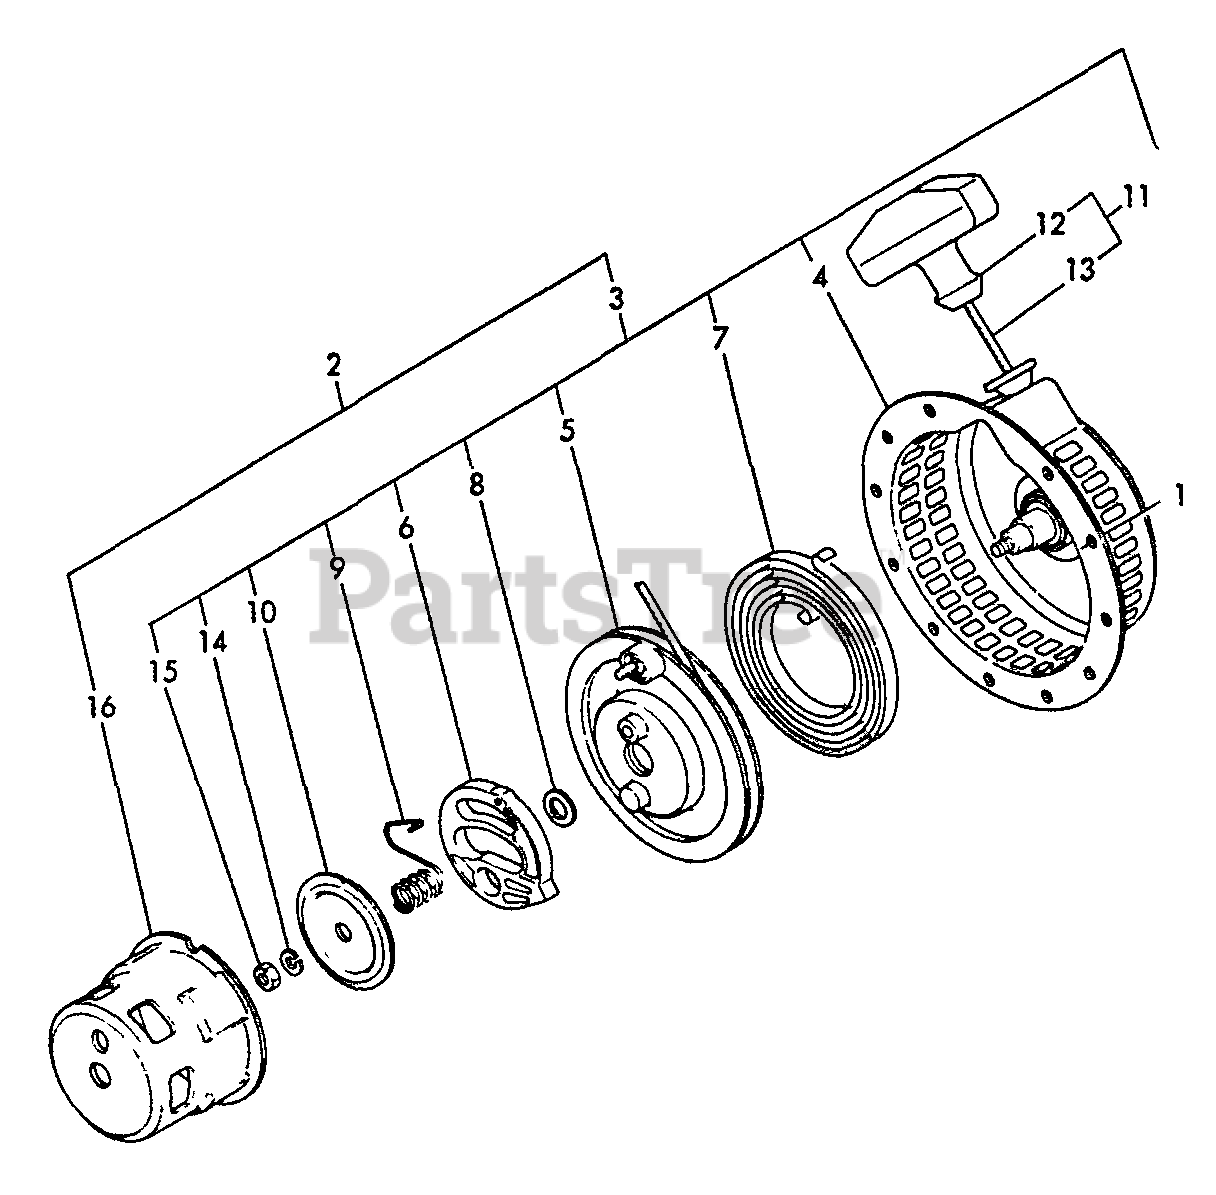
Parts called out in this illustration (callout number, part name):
1	BOLT - 6×12 -- PLATED
2	STARTER ASSY, RECOIL
3	STARTER ASSY, RECOIL
4	CASE, STARTER
5	REEL
7	SPRING, SPIRAL
8	WASHER
9	SPRING
10	PLATE, FRICTION
11	STARTER ROPE ASSY
12	GRIP, STARTER
13	ROPE, STARTER
14	LOCKWASHER - 6
15	NUT - 6
16	PULLEY, STARTER
